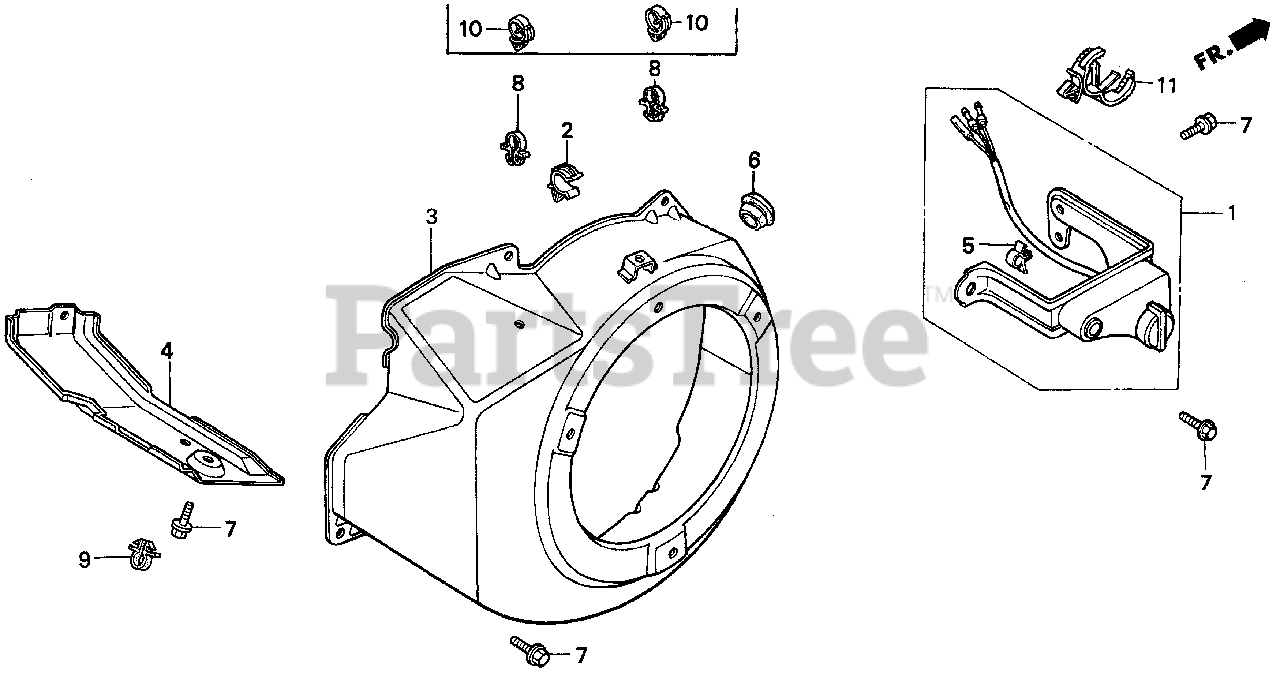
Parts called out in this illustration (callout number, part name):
1	ALERT UNIT, OIL
2	CLIP, TUBE
4	SHROUD
5	CLIP, IGNITION WIRE (8MM)
6	GROMMET, DRAIN HOLE
7	BOLT, FLANGE (6X12) (CT200)
11	CLIP, WIRE HARNESS
